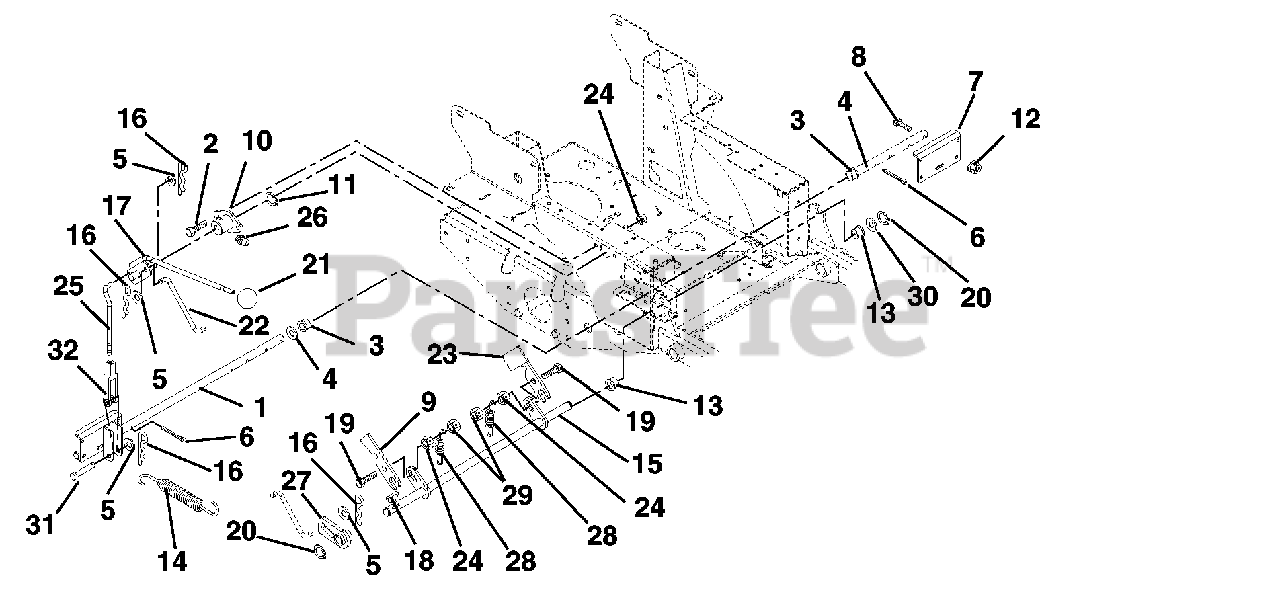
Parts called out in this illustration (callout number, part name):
1	Weldment, Brake Shaft
2	Bolt, Hex .31-18 x .75 Grade 5
3	Bushing, Flange .762 x 1.00 x .58 x 1.48 Nylon
4	Washer, Flat Steel .755 x 1.375 x .062
5	Washer, Flat Steel .406 x .812 x .065
6	Pin, Cotter .12 x 1.00 Extended Prong Square Cut
7	Paddle, Brake
8	Bolt, Hex .25-20 x 1.25 Grade 5
9	Slide, Interlocking Brake
10	Bushing, Flange
11	Ring, Retaining External .625 x .05
12	Nut, Locking Top Flange .25-20
13	Bushing, Flange .50 x .75 x .75 x 1.00
14	Spring, Engine Transmission
15	Weldment, Mechanical Brake
16	Pin, Hair
17	Weldment, Brake Actuating
18	Key, Woodruff .13 x .63
19	Bolt, Hex .31-18 x 1.25 Grade 5
20	Ring, Retaining External .50 x .05
21	Knob, Steering Lock
22	Linkage, Brake Actuating
23	Interlock, Safety Switch
24	Nut, Locking Top Flange .31-18
25	Linkage, Brake Compact-Z
26	Fitting, Lube .25-28 x .256
27	Weldment, Parking Brake Hub
28	Spring, Tension .061 x .50 x 3.0
29	Nut, Locking Center .31-18
30	Washer, Flat Steel .505 x 1.00 x .062
31	Pin, Clevis .37 x 1.75
32	Clevis,.38-24 Adjustable
